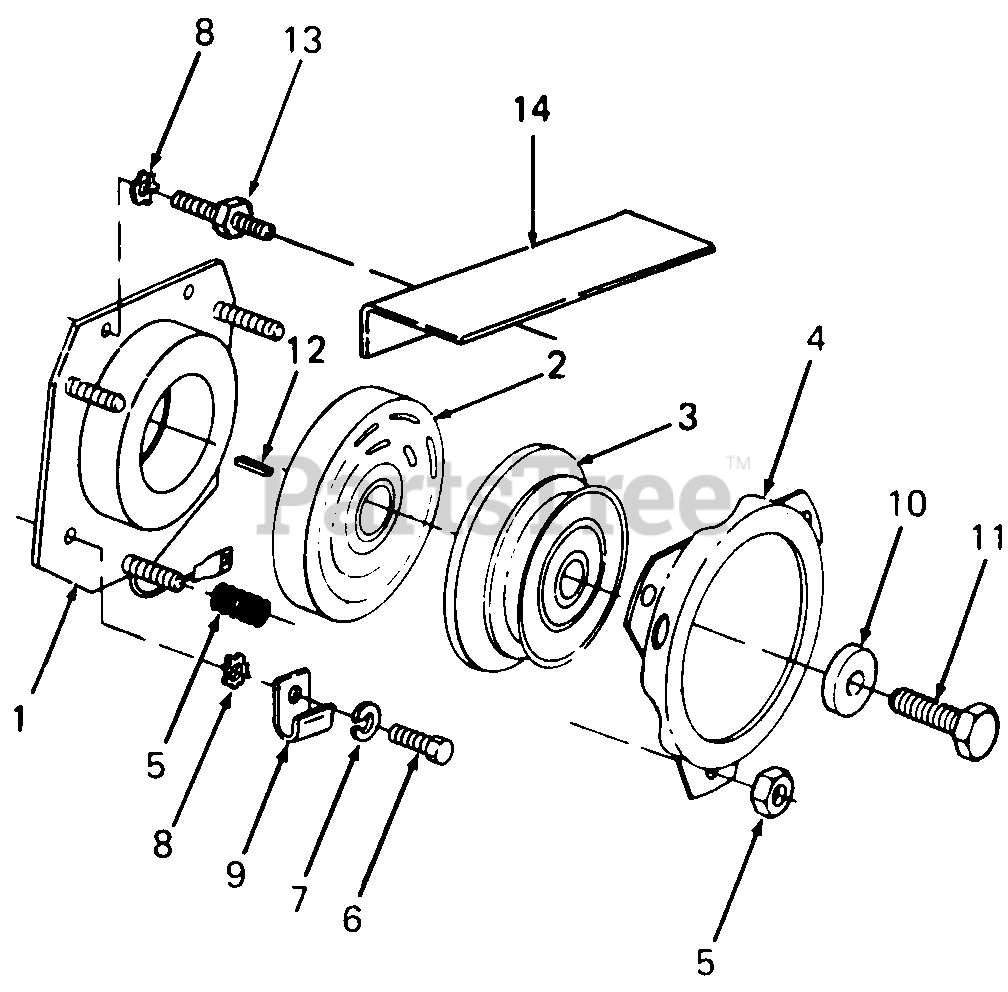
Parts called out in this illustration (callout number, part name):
4	Drum, Brake
5	Spring & Nut Kit
6	Screw, Hex Cap, 7/16-14 X .75 Lg GR5
7	Washer, Lock, 7/16
8	Washer, Ext. Lock, .45 X .75 X .035 Thk
9	Clamp, Cable
10	Washer, Flat, .47 X 1.5 X .225 Thk
11	Screw, Hex Cap, 7/16-20 X 1.25 Lg GR5
12	Key, Square, 1/4 X .75 Lg
13	Stud, 7/16-14 Trd
14	Baffle, PTO
